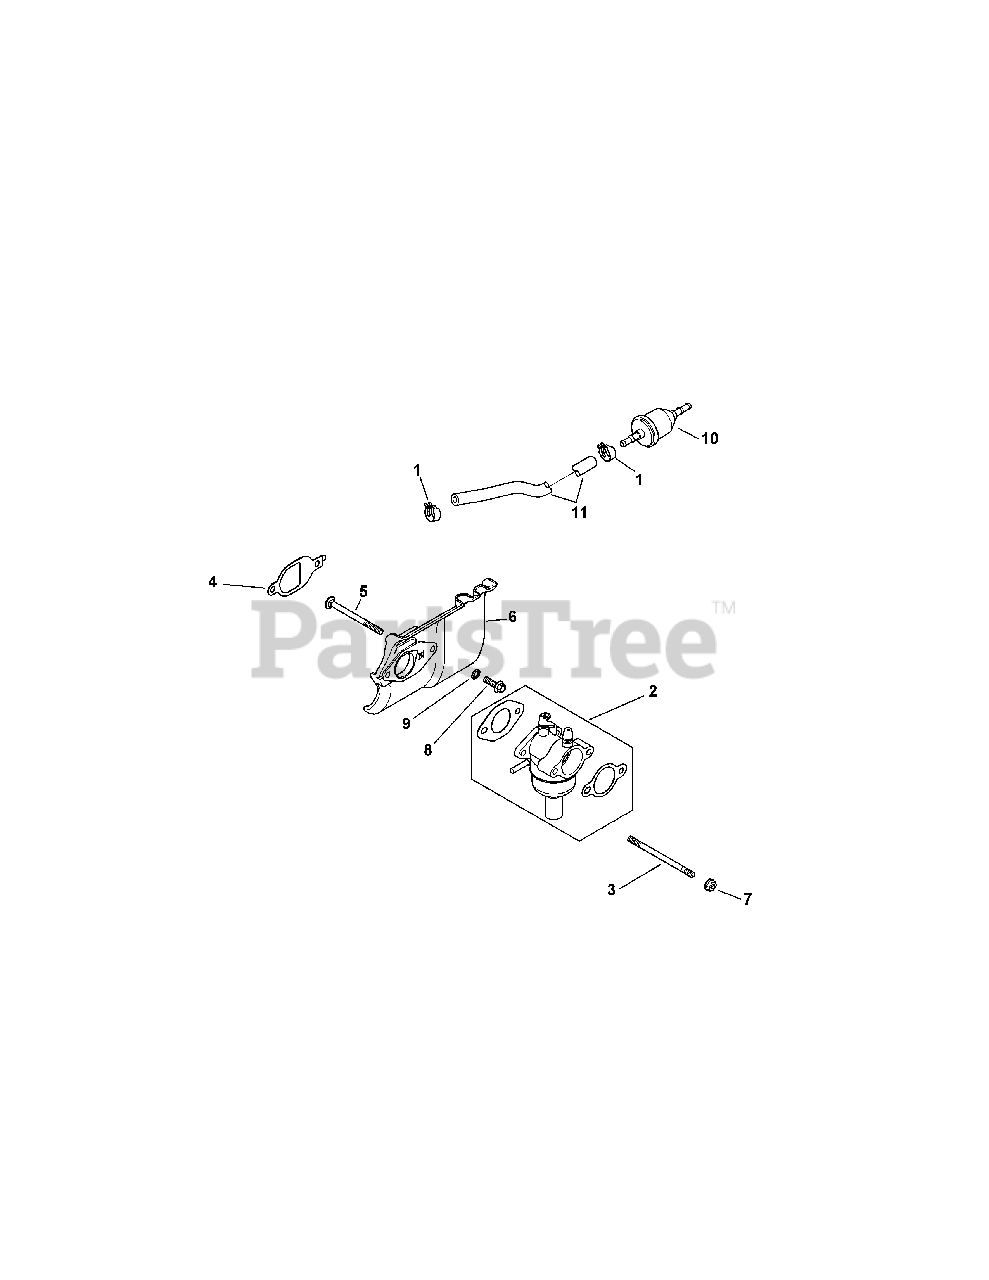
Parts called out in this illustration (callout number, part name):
1	Hose Clamp, 1/2
2	Carburetor Kit
2	Carburetor Gasket
2	A/C Base Gasket
3	Stud, M6 X 1.0 X 100
4	Heat Deflector Gasket
5	Carburetor Stud
6	Heat Deflector Kit
7	Flange Nut, M6 X 1.0
8	Flange Screw, M6 X 1.0 X 20
9	Int. Tooth Lock Washer, 1/4
11	Fuel Line
